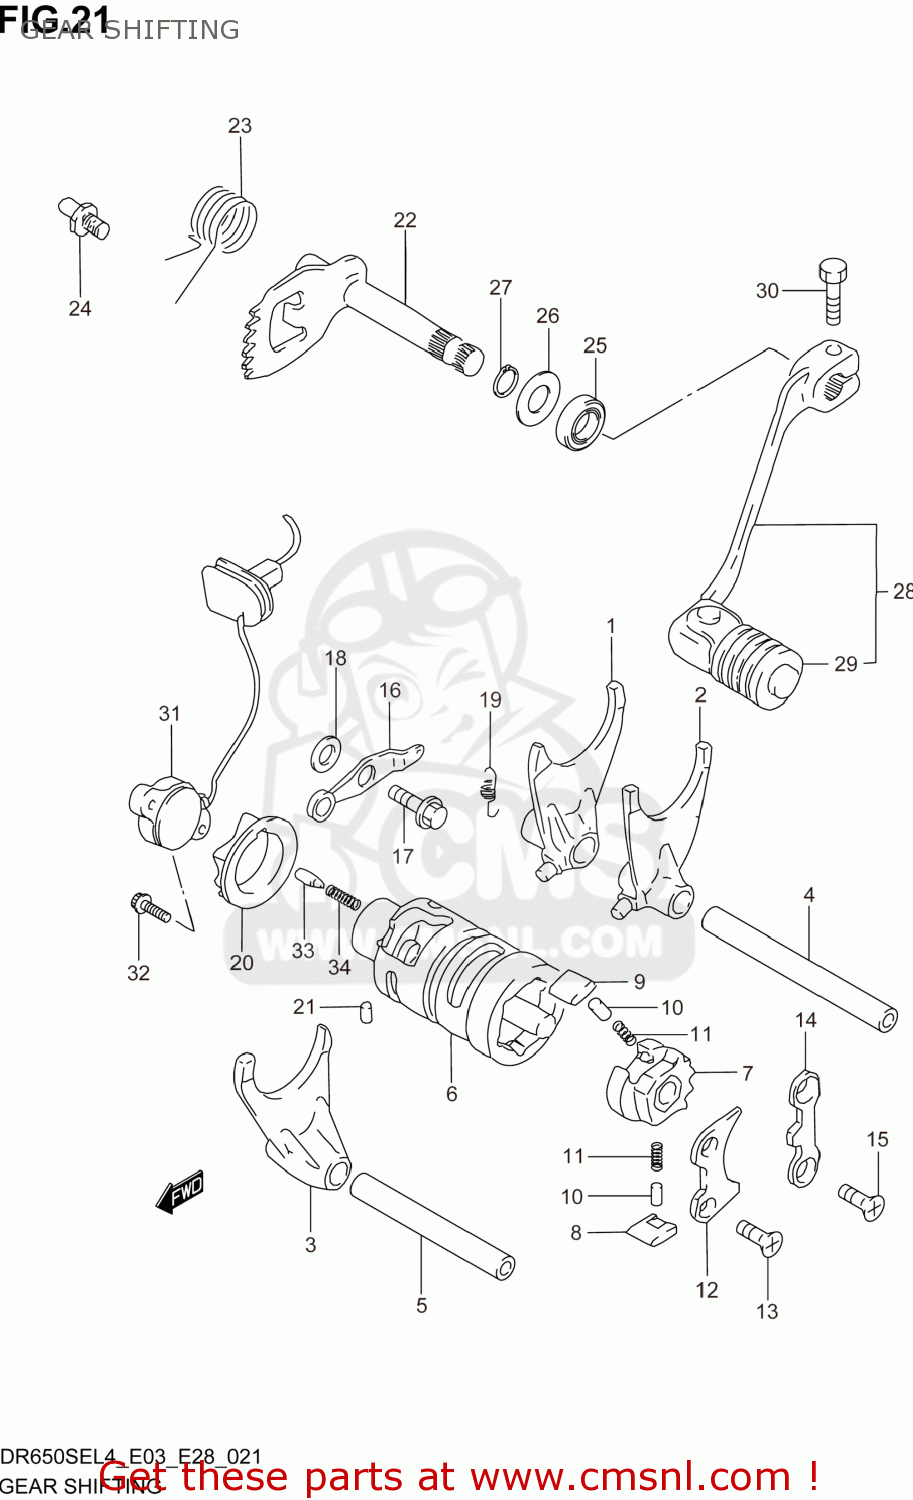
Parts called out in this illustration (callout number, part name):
1	FORK,GEAR SHIFT NO.1
2	FORK,GEAR SHIFT NO.2
3	FORK,GEAR SHIFT NO.3
4	SHAFT,GEAR SHIFT FORK
5	SHAFT,GEAR SHIFT FORK
6	CAM,GEAR SHIFT
7	GEAR,GEAR SHIFT CAM DRIVEN
8	PAWL,GEAR SHIFT NO.1
9	PAWL,GEAR SHIFT NO.2
10	PIN(5X8)
11	SPRING
12	LIFTER,GEAR SHAFT PAWL
13	SCREW(6X12)
14	STOPPER,GEAR SHIFT POLE
15	SCREW(6X12)
16	STOPPER,GEAR SHIFT CAM
17	BOLT(6X14.6)
18	WASHER
19	SPRING
20	PLATE,GEAR SHIFT CAM STOPPER
21	PIN
22	SHAFT,GEAR SHIFT
23	SPRING
24	STOPPER,GEAR SHIFT ARM
25	SEAL,OIL (12X22X9)
26	WASHER
27	CIRCLIP
28	LEVER ASSY,GEAR SHIFT
29	RUBBER,GEAR SHIFT PEDAL
30	BOLT
31	BASE ASSY,NEUTRAL SW TERMINAL
32	BOLT
33	PIN(5X15.5)
34	SPRING
